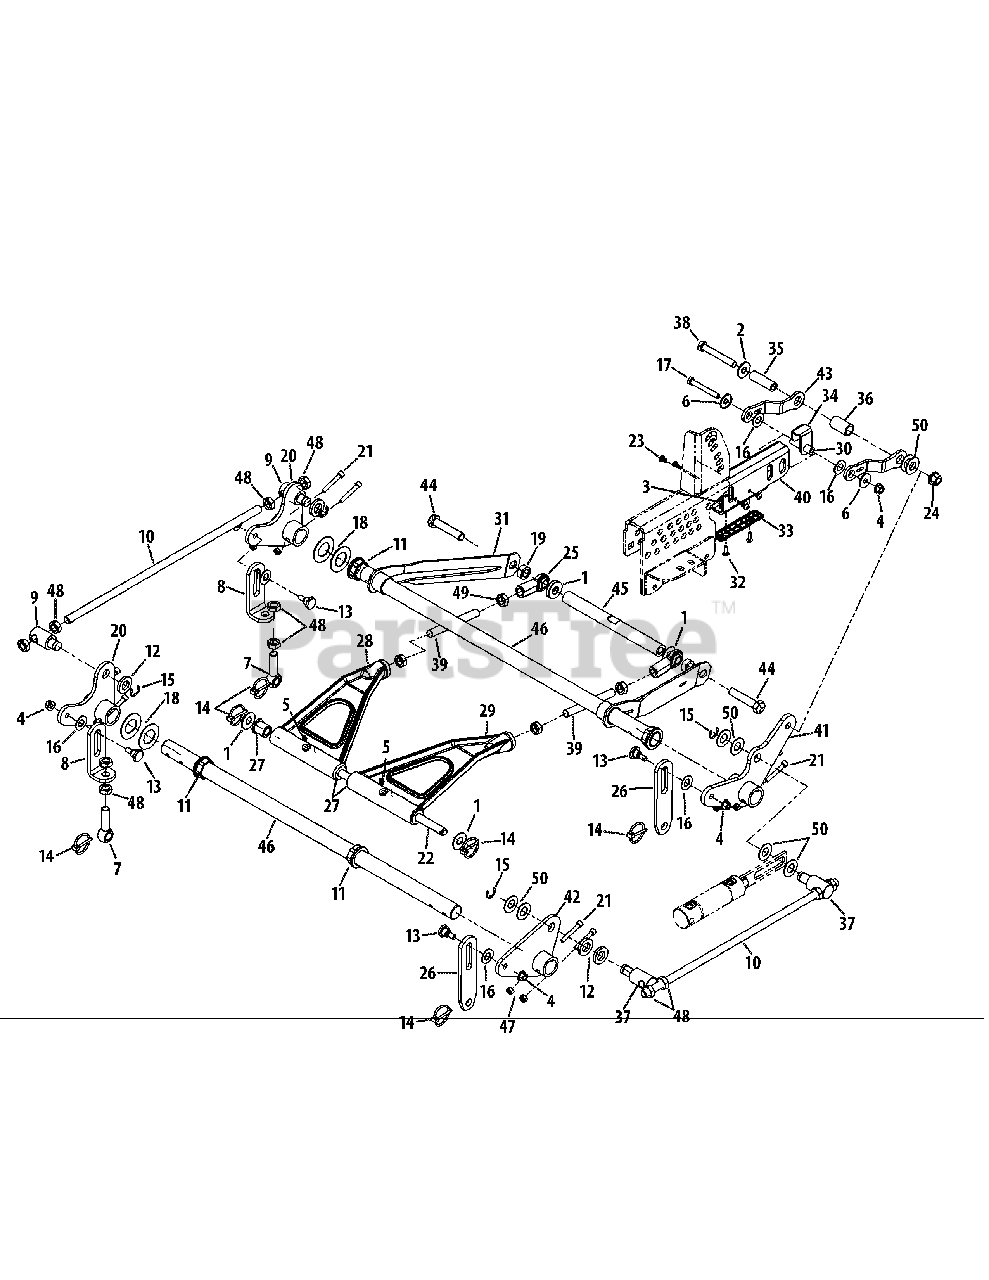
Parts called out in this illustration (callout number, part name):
1	Washer, .655 x 1.5 x .055
2	Washer, .563 x 1.38 x .109
3	Nut, 1/4-20
4	Flg. Cnter. Lock Nut, 3/8-16 (60" Deck)
4	Flange Lock Nut, 3/8-16 (72" Deck)
5	Grease Fitting, 1/4-28
6	Washer, .411 x 1.25 x 1.00
7	Eye Bolt, 5/8-16 x 2.63
8	Eye Bolt Link, 5/8
9	Lift Ferrule
10	Lift Connecting Rod
11	Hex Flange Bearing
12	Spacer, .812 x 1.47 x .218
13	Shoulder Bolt, 3/8-16 x .625 x .437
14	Lynch Pin, 3/16 x 1.25
15	Retainer Clip
16	Washer
17	Hex Screw, 3/8-16 x 3.00
18	Washer, 1.25 x 2.25 x .075
19	Spacer, .630 x 1.06 x .440
20	Assembly Bellcrank
21	Screw, 5/16-18 x 2.0
22	Deck Lift Link Rod (60" Deck)
22	Deck Lift Link Rod (72" Deck)
23	Rivet, 1/4 x .625
24	Flange Top Lock Nut, 1/2-13
25	RH Rod End, 5/8
26	Deck Lift Link
27	Flange Bearing
28	LH Lift Link Casting
29	RH Lift Link Casting
30	Spacer, .375 x .625 x 2.20
31	Front Frame Support Assembly
32	Flat Head Screw, 1/4-20 x .750
33	Wear Plate, 1.125 x 5.0
35	Spacer, .510 x .750 x 2.38
36	Spacer, .765 x 1.00 x 1.70
37	Lift Ferrule, 1.938
38	Hex Screw, 1/2-13 x 3.5
39	Rod, 5/8-18 x 5.5 (60" Deck)
39	Rod, 5/8-18 x 3.5 (72" Deck)
40	Tube, 3.0 x 1.5
41	Hydro Assist Bellcrank
42	Lift Bellcrank Assembly
43	Loft Off set Yoke Bracket
44	Hex Screw, 5/8-11 x 3.00
45	Front Lift Link Mount Shaft
46	Deck Lift Shaft
47	Hex Lock Nut, 5/16 -18
48	Jam Nut, 5/8-11
49	Jam Nut, 5/8-18
50	Flat Washer, .76 x 1.49 x .06
